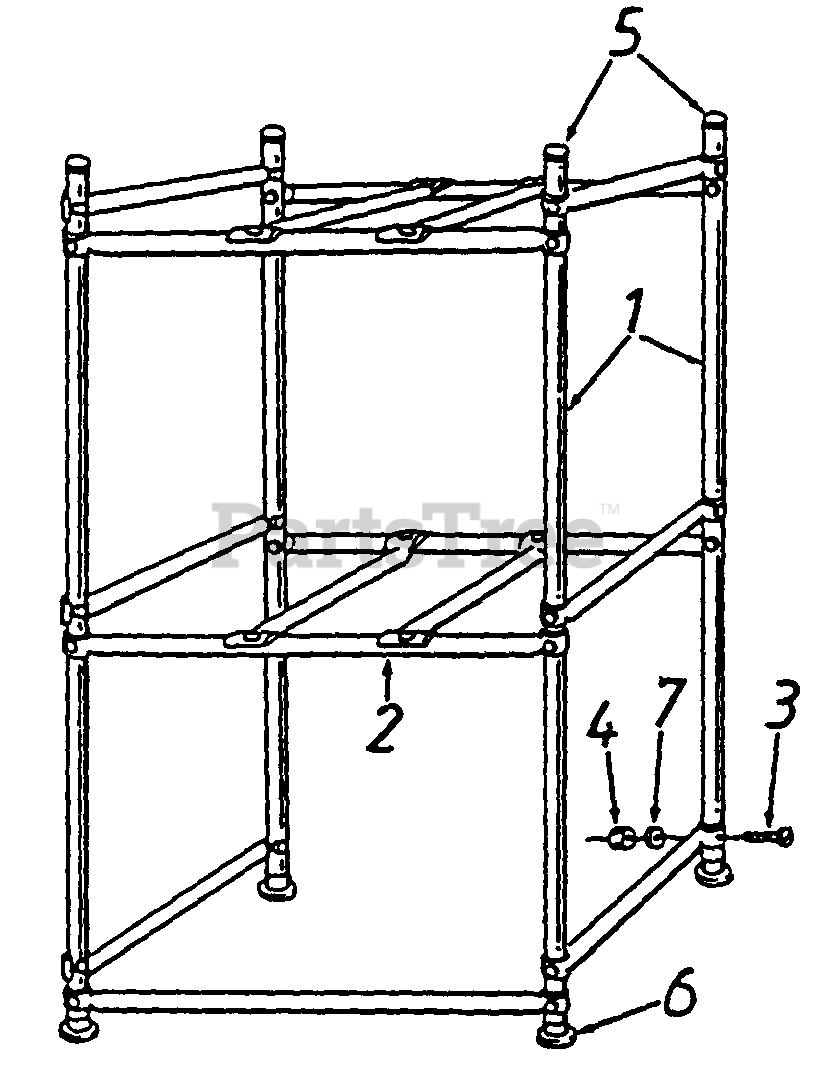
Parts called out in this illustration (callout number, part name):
4	Hex Nut 1/4-20 Thd.
5	1" Tubing Plug (Installed)
6	1" Swivel Guide (Installed)
7	Lock Washer 1/4" I.D.
